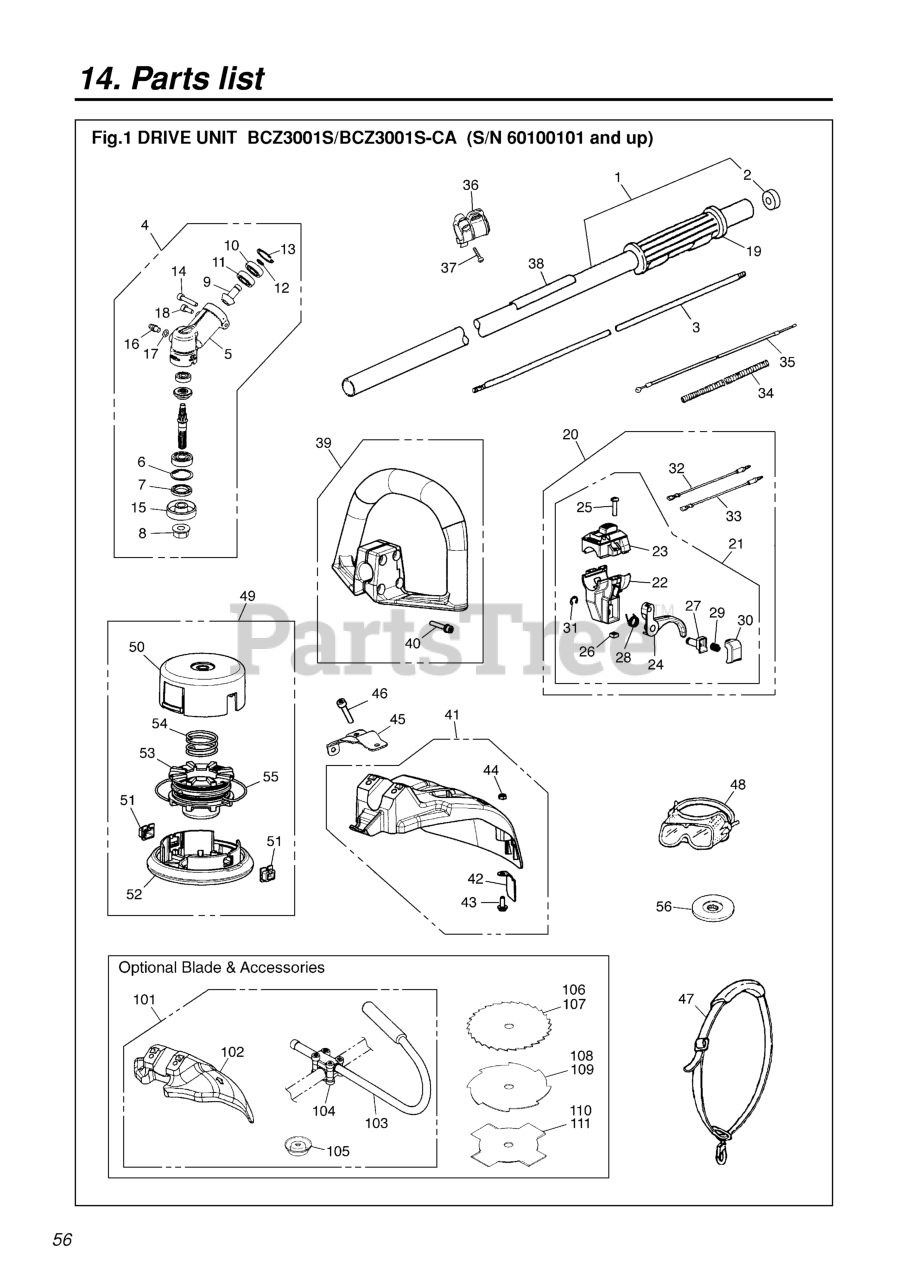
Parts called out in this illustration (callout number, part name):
1	PIPE COMP.
2	SEAL
3	SHAFT (RPLS -12212)
4	GEARCASE ASSY.
5	GEARCASE
6	RING, SNAP, M26 X 1.2
7	SEAL, OIL
8	NUT
9	PINION
13	RING, SNAP, M24 x 1.2
14	BOLT, TORX
15	HOLDER (A)
16	FITTING, GREASE
17	WASHER, M6 X .8
18	BOLT, TORX
19	GRIP
20	LEVER ASSY
21	LEVER
23	COVER
24	FLEX, TRIGGER
32	CORD (A), BLACK
33	CORD (B), RED
34	TUBE (RPLS 4900-72141)
35	CABLE (RPLS 5580-83100)
36	HANGER COMP.
37	SCREW
38	NAME PLATE
39	HANDLE ASSY. (REPLACES -14001)
40	SCREW
41	GUARD COMP.
42	BLADE (RPLS T3002-24120)
43	SCREW TORX
44	NUT
45	BRACKET
46	BOLT, TORX
47	STRAP ASSY. (USE 848-JC0-3610)
48	GOGGLE
49	TAP HEAD COMP.
50	CASE (REPLACES -15111)
51	EYELET
52	COVER (REPLACES -15131)
53	HOLDER, CORD (REPLACES-15141)
54	SPRING
55	CORD
56	HOLDER (B)
101	BLADE KIT
102	GUARD
103	HANDLE, J
104	BRACKET ASSY.
105	COVER
106	BLADE, 9
107	BLADE, 9
108	BLADE, 8
109	BLADE, 9
110	BLADE, 8
111	BLADE, 9
